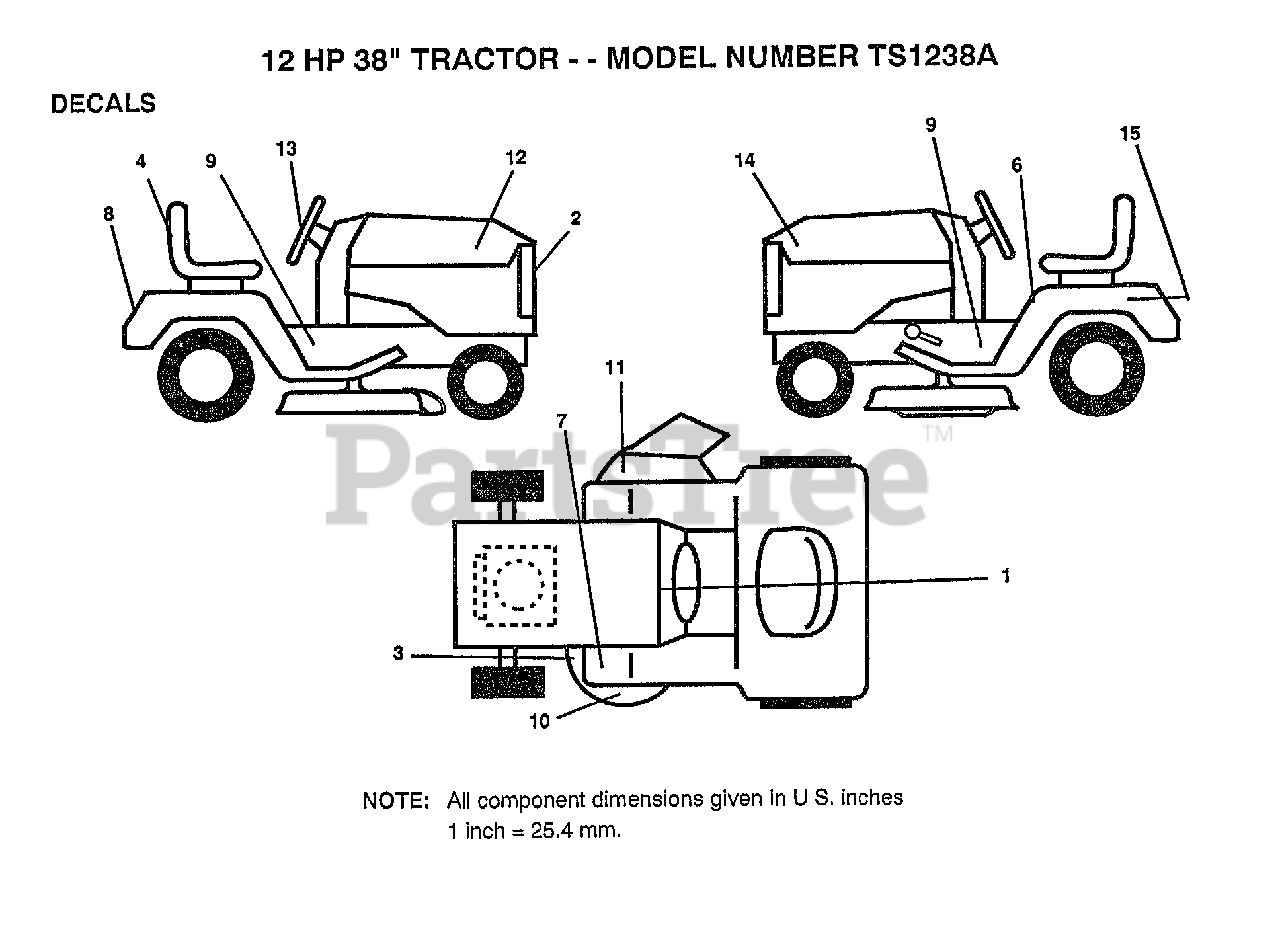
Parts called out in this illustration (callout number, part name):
1	DECAL.DASH.INSTR.
2	DECAL.GRILL.HUSKE
3	DECAL
4	DECAL.SEAT.AM.FLG
6	DECAL CAUTION
7	DECAL T
8	DECAL.FENDER.HUSK
9	DECAL.CHASSIS.12H
11	"DECAL, WARNING"
12	DECAL.HOOD.RH
13	DECAL.STRG.WHL
14	DECAL.HOOD.LH
15	DECAL
